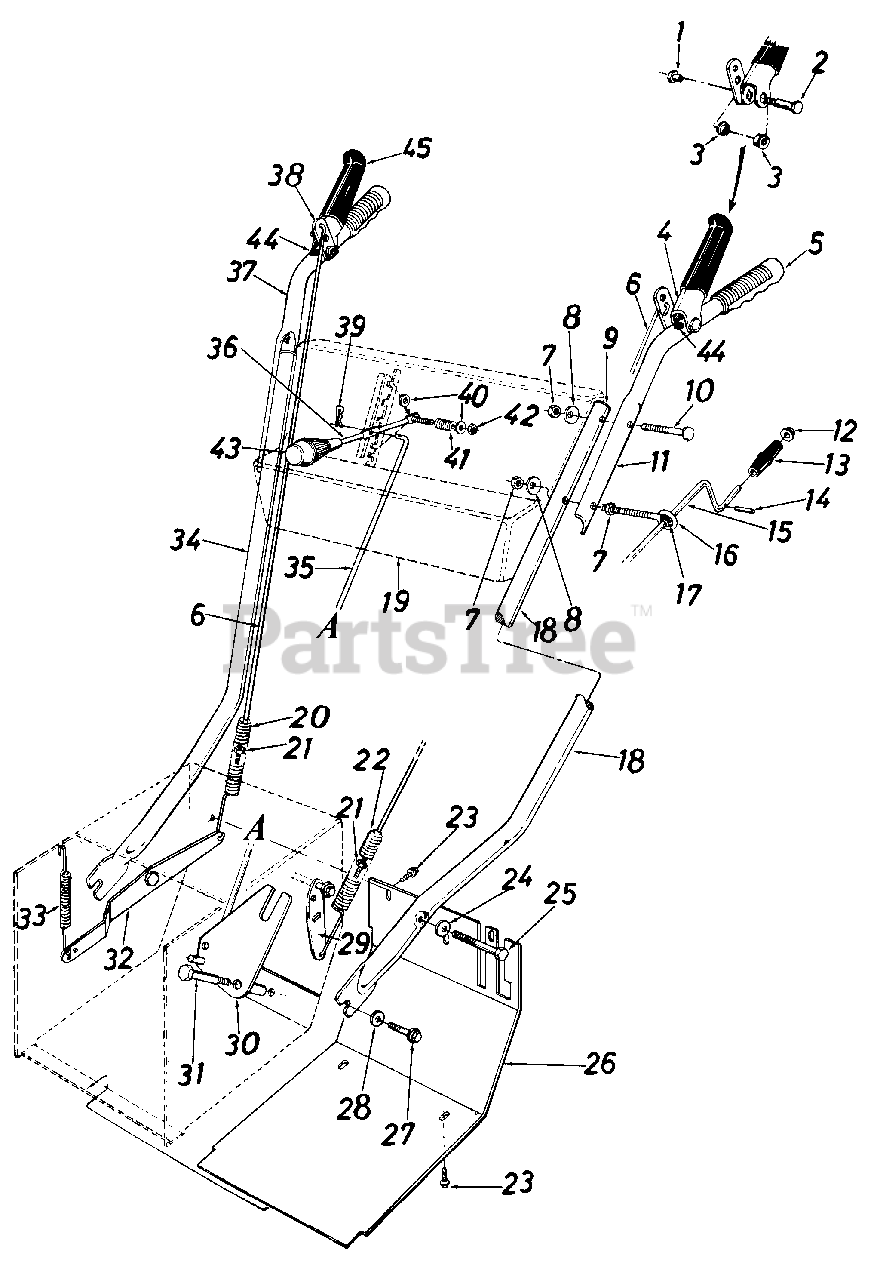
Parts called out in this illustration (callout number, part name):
1	Shld. Nut 1/4-20 Thd.
2	Shld. Bolt .374 Dia. x 1.375" Lg.
3	Hex Flange Plastic Bearing .38" I.D.
4	Clutch Grip Ass'y.-L.H.
5	Grip-Red
6	Lockout Rod
7	Hex Nut 5/16-18 Thd.
8	Bell-Wash. .34" I.D. x .88" O.D.
9	Plastic Plug
10	Curved Carriage Bolt 5/16-18 x 2.0" Lg.
11	Upper Handle-L.H. (Painted)
12	Push Nut 3/8" Rod
13	Knob 3/8" Rod
14	Roll Pin .12 Dia. x .631" Lg.
15	Chute Crank Ass'y.
16	Eye Bolt 5/16-18 x 5.0" Lg.
17	Plastic Bushing
18	Lower Handle-L.H. (Painted)
19	Handle Panel Ass'y.
20	Extension Spring .75" O.D. x 5.0" Lg.
21	Hex Ins. L-Nut 1/4-20 Thd.
22	Extension Spring .75" O.D. x 5.0" Lg.
23	Hex Wash. Hd. Self-Tap Scr. 5/16-24 x .50" Lg.
24	Bell-Wash. .40" I.D. x .88" O.D.
25	Hex Bolt 3/8-16 x 2.0" Lg.
26	Frame Cover
27	Pilot Hex Scr. 3/8-16 x .88" Lg.
28	Bell-Wash. .40" I.D. x .88" O.D.
29	Drive Clutch Brkt. Ass'y.
32	Auger Clutch Brkt.
33	Extension Spring .38" O.D. x 3.18" Lg.
34	Lower Handle-R.H. (Painted)
35	Shifting Rod
36	Shift Handle
38	Clutch Grip Ass'y.-R.H.
39	Int. Cotter Pin 5/16" Dia.
40	Fl-Wash. .344" I.D. x .62" O.D.
41	Compression Spring
42	Hex Ins. L-Nut 5/16-18 Thd.
44	Push Cap
45	Black Vinyl Grip
